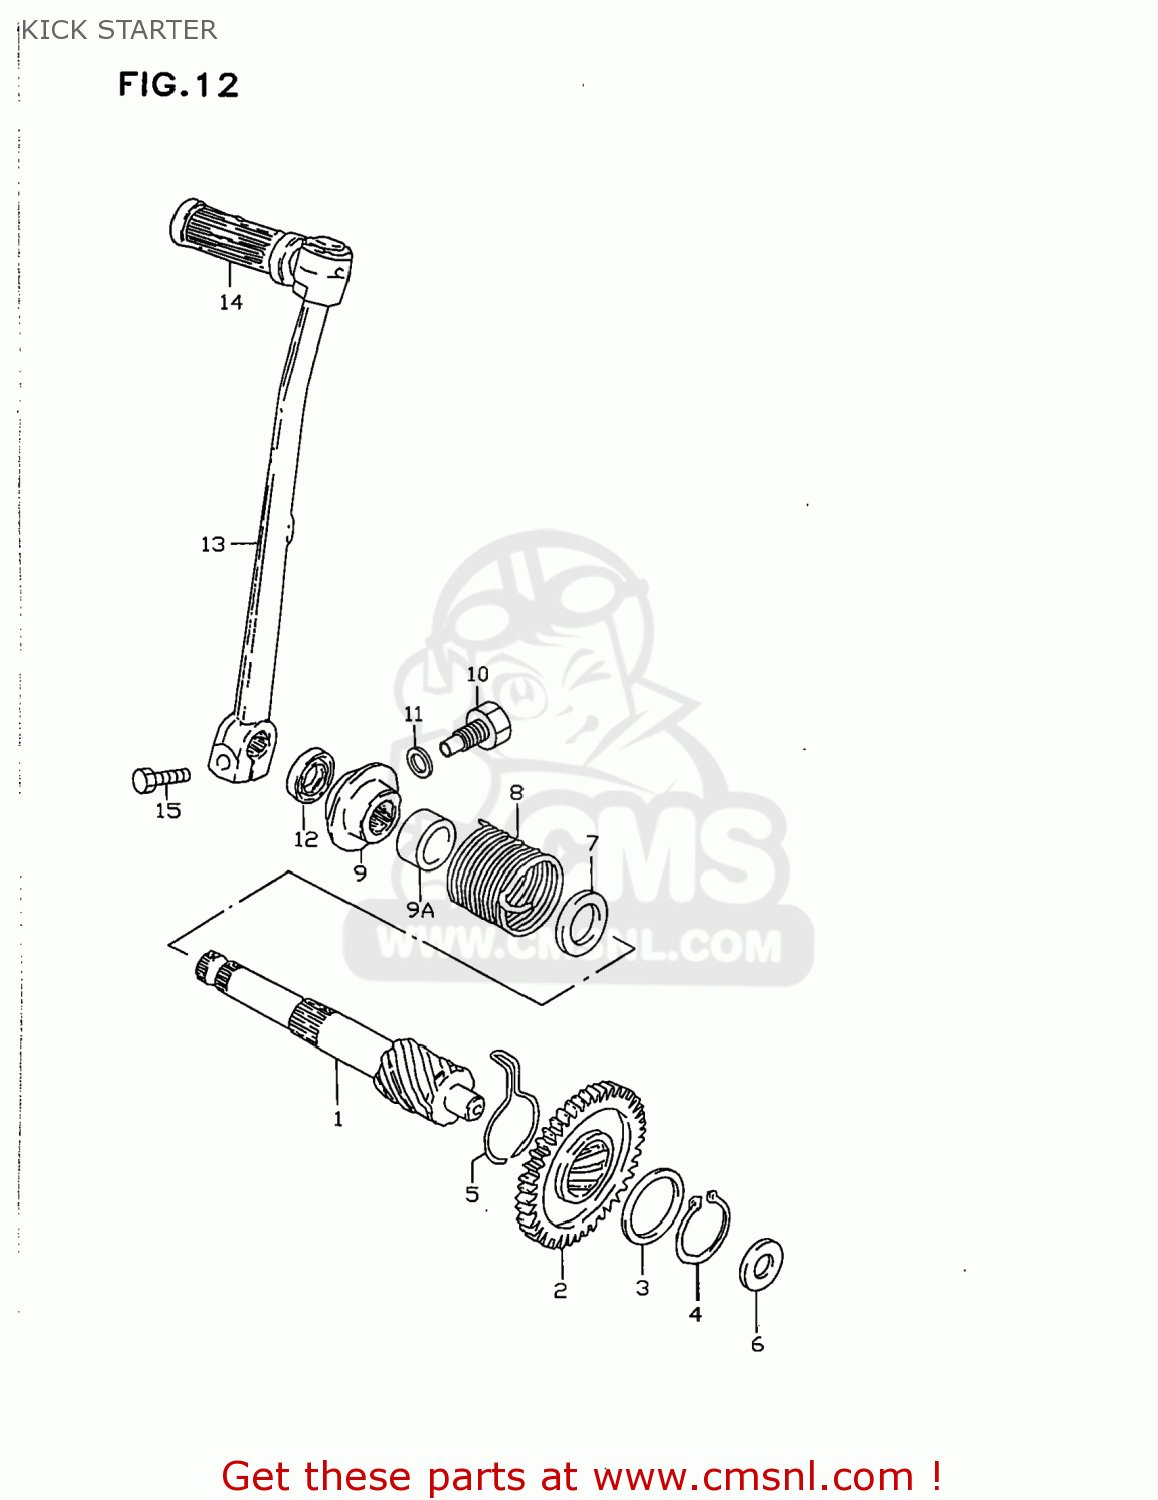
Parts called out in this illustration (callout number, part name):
1	SHAFT,KICK STARTER
2	GEAR,KICK STARTER DRIVE
3	WASHER
4	CIRCLIP
5	RETAINER,SNAP
6	WASHER
7	WASHER(16X30X1)
8	SPRING
9	LIFTER,KICK STARTER
9A	GUIDE,KICK RETURN SPRING
10	BOLT(10X17)
11	GASKET(10X14X3.6) (NAS)
12	SEAL,OIL(14X24X6)
13	LEVER ASSY,KICK STARTER
14	RUBBER,KICK STARTER PEDAL
15	BOLT
